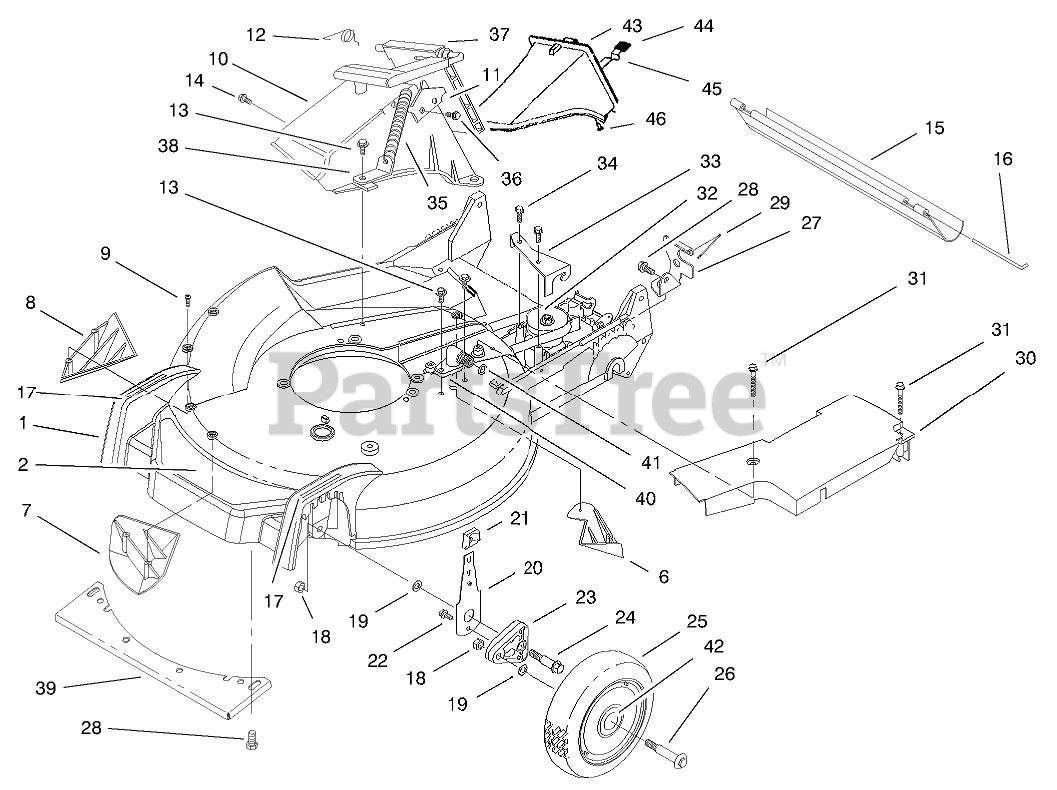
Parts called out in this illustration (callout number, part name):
1	Housing-Rwd (Incl. Ref. #5-9, 13, 17, 28, & 39-41)
2	DECAL - DECK
6	KICKER-REAR
7	KICKER-FRONT
8	KICKER-RH
9	SCREW-PPH
10	TUNNEL-DISCHARGE
11	LATCH-PLATE
12	RETAINER-DOOR
13	SCREW-HWH
14	SCREW AND WASHER ASM
15	SHIELD-TRAILING
16	ROD-SHIELD
17	DECAL - HOC
18	NUT-LOCK
19	WASHER
20	FRONT SPRING ARM ASM
21	KNOB-ARM
22	SCREW-HWH
23	ARM-PIVOT, FRONT
24	BOLT-SHOULDER
25	ASM-Wheel & Tire (Incl. Ref. #42)
26	BOLT-WHEEL
27	Bracket-Adj. Trac
28	SCREW-HWHTF
29	RETAINER-CABLE
30	BELT COVER
31	SCREW-HHFTF
32	GEARCASE ASM
33	Bracket-Guide
34	SCREW-HWHTF
35	SPRING-DOOR
36	SCREW-PLASTITE
37	DISCHARGE DOOR ASM
38	BRACKET-SPRING
39	Shield-front
40	FITTING-WASHOUT
41	O-RING
42	BUSHING
43	Plug-Discharge ASM (Incl. Ref. #44-46)
44	GRIP-LATCH
45	LATCH-PLUG, DISCHARGE
46	RIVET-HEAD, FLAT
